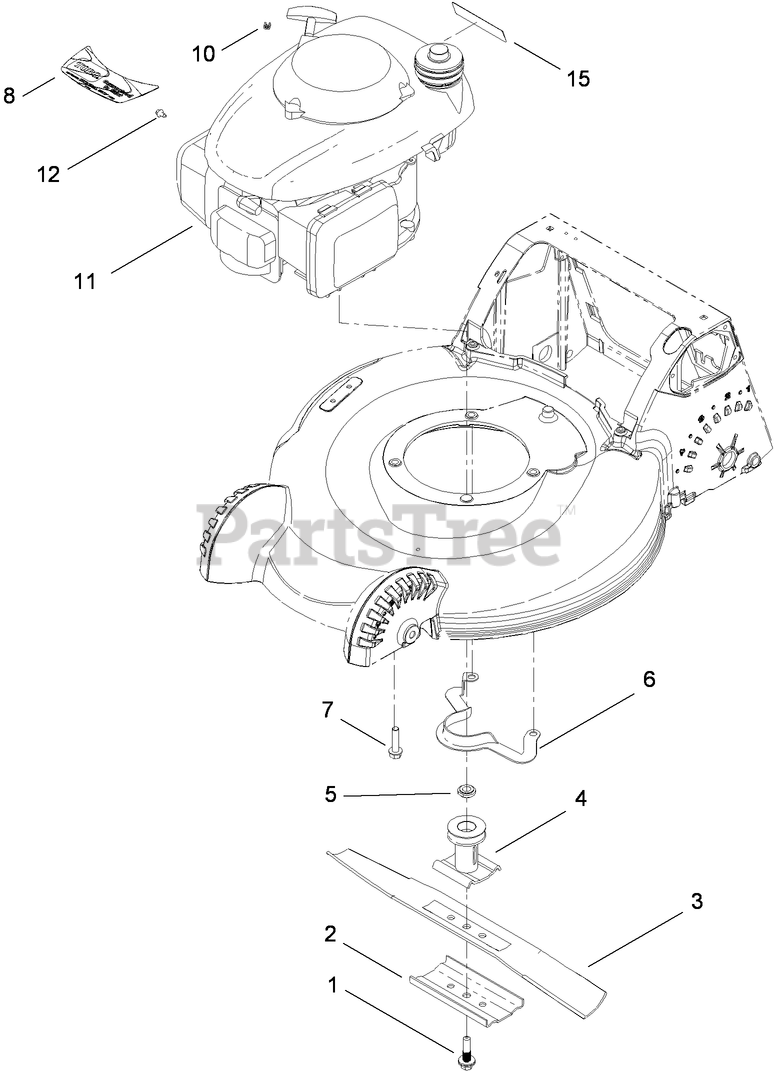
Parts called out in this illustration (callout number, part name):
1	BOLT-BLADE
2	SUPPORT-BLADE
3	BLADE-BAGGING
4	DRIVER-BLADE
5	Spacer-Driver
6	GUIDE-BELT
7	SCREW-HWH
8	DECAL-ENGINE
10	STOP-ROPE
11	ENGINE-HONDA, GCV160LA0 S3T
12	SCREW-HWH
15	DECAL-ARRESTER, SPARK
